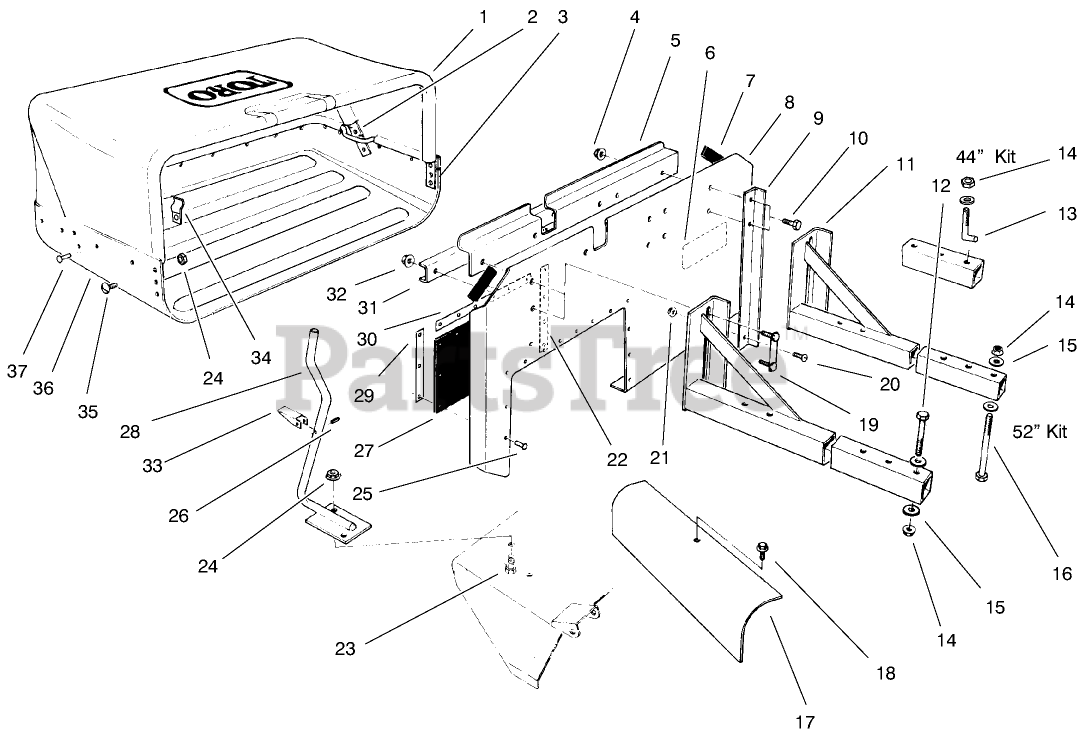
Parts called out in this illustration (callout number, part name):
1	Bag-Cloth
2	Rod-Cloth
3	Tube-Bag Support
4	NUT-HHF, WHIZ
5	Support-Bag
6	DECAL-DANGER
7	PAD-RUBBER
8	Panel-Back
9	Support-Panel
10	SCREW-HH
11	Beam-Mounting
12	SCREW-HH
13	Bolt-Special
14	NUT-LOCK, NI
15	WASHER-FLAT
16	SCREW-HH
17	Baffle-44in
18	Screw-HH
19	Retainer-Bolt
21	NUT-HF
22	STRIP-Seal, 10in
23	SCREW-HH
24	NUT-HF
25	RIVET-POP
26	PIN-SPRING
28	Rod-Lockup
29	STRIP
30	STRIP-SEAL, 16in
31	Support-Channel
32	NUT-LOCK, FLANGE
33	LATCH-LOCKUP
34	CLIP-HALF
35	SCREW-PPH
36	TRAY-BAG, GRASS
37	RIVET-BLIND
